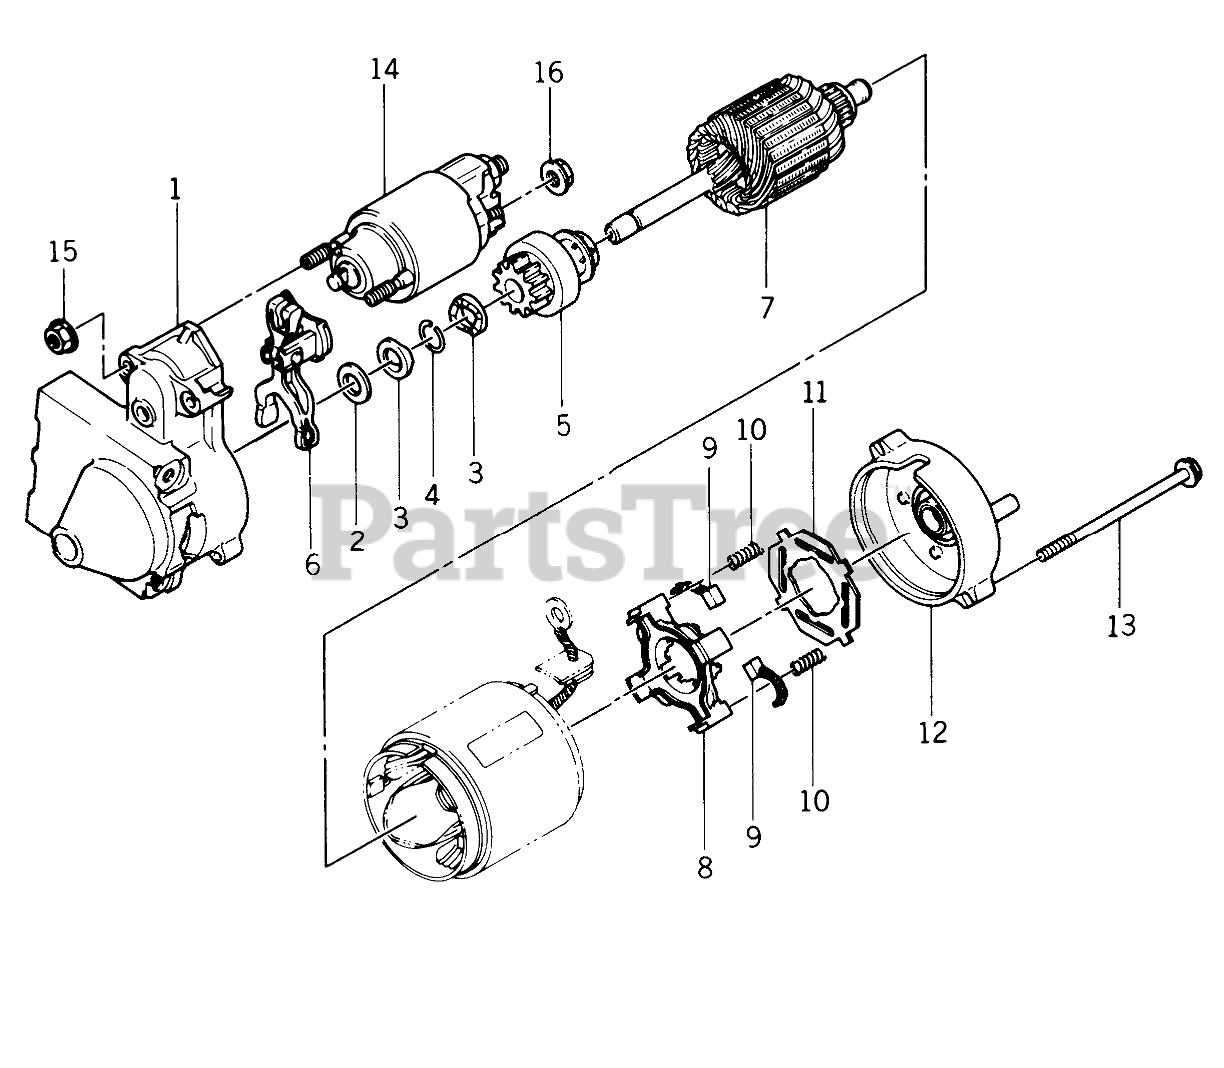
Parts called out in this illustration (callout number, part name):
1	COVER ASSY
2	WASHER
3	STOPPER
4	RING-SNAP
5	CLUTCH ASSY
6	LEVER-SHIFT
7	ARMATURE
8	HOLDER-BRUSH
9	BRUSH
10	SPRING-BRUSH
11	INSULATOR
12	COVER ASSY
14	SWITCH ASSY
